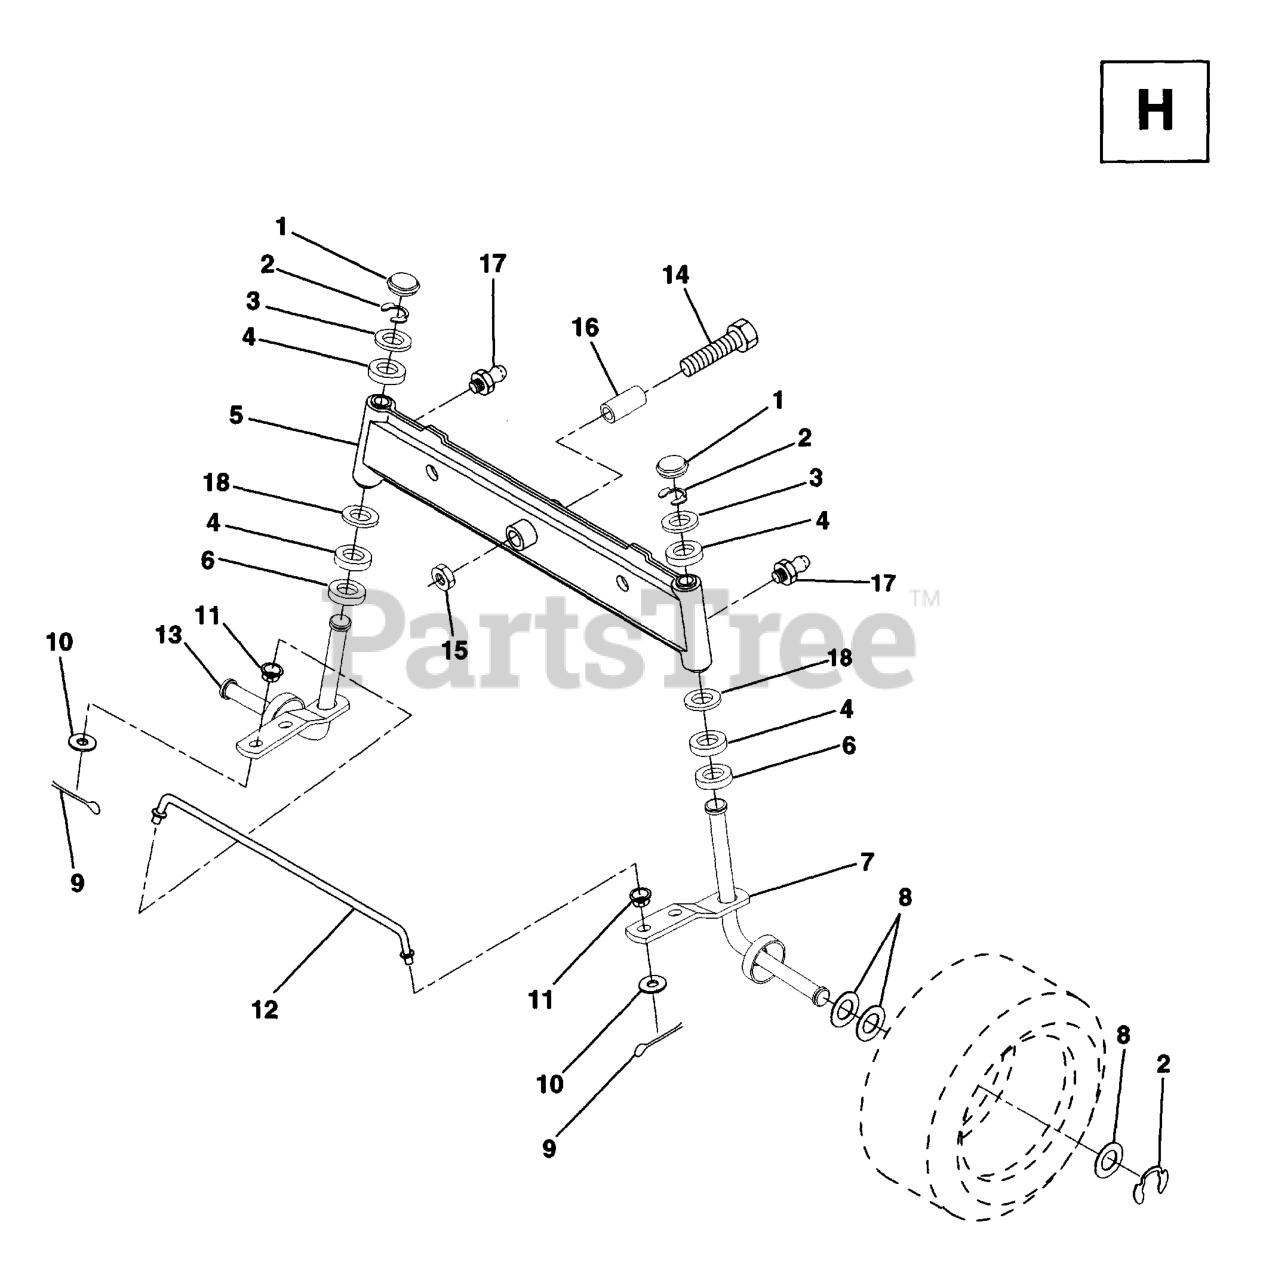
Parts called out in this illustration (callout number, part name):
1	CAP.SPINDLE.BLACK
4	BRNG T
6	THRUST WASHER
7	SPINDLE ASSY RH NLA
9	COTTER PIN
10	WASHER
11	BUSHING.DRAGLINK (2 2)
12	TIE ROD
13	SPINDLE ASSY LH
14	Bolt, Hex Head 5/8-11 x 3-1/2
15	NUT-LOC,FLANGE LT
16	BEARING
17	ZERK M
